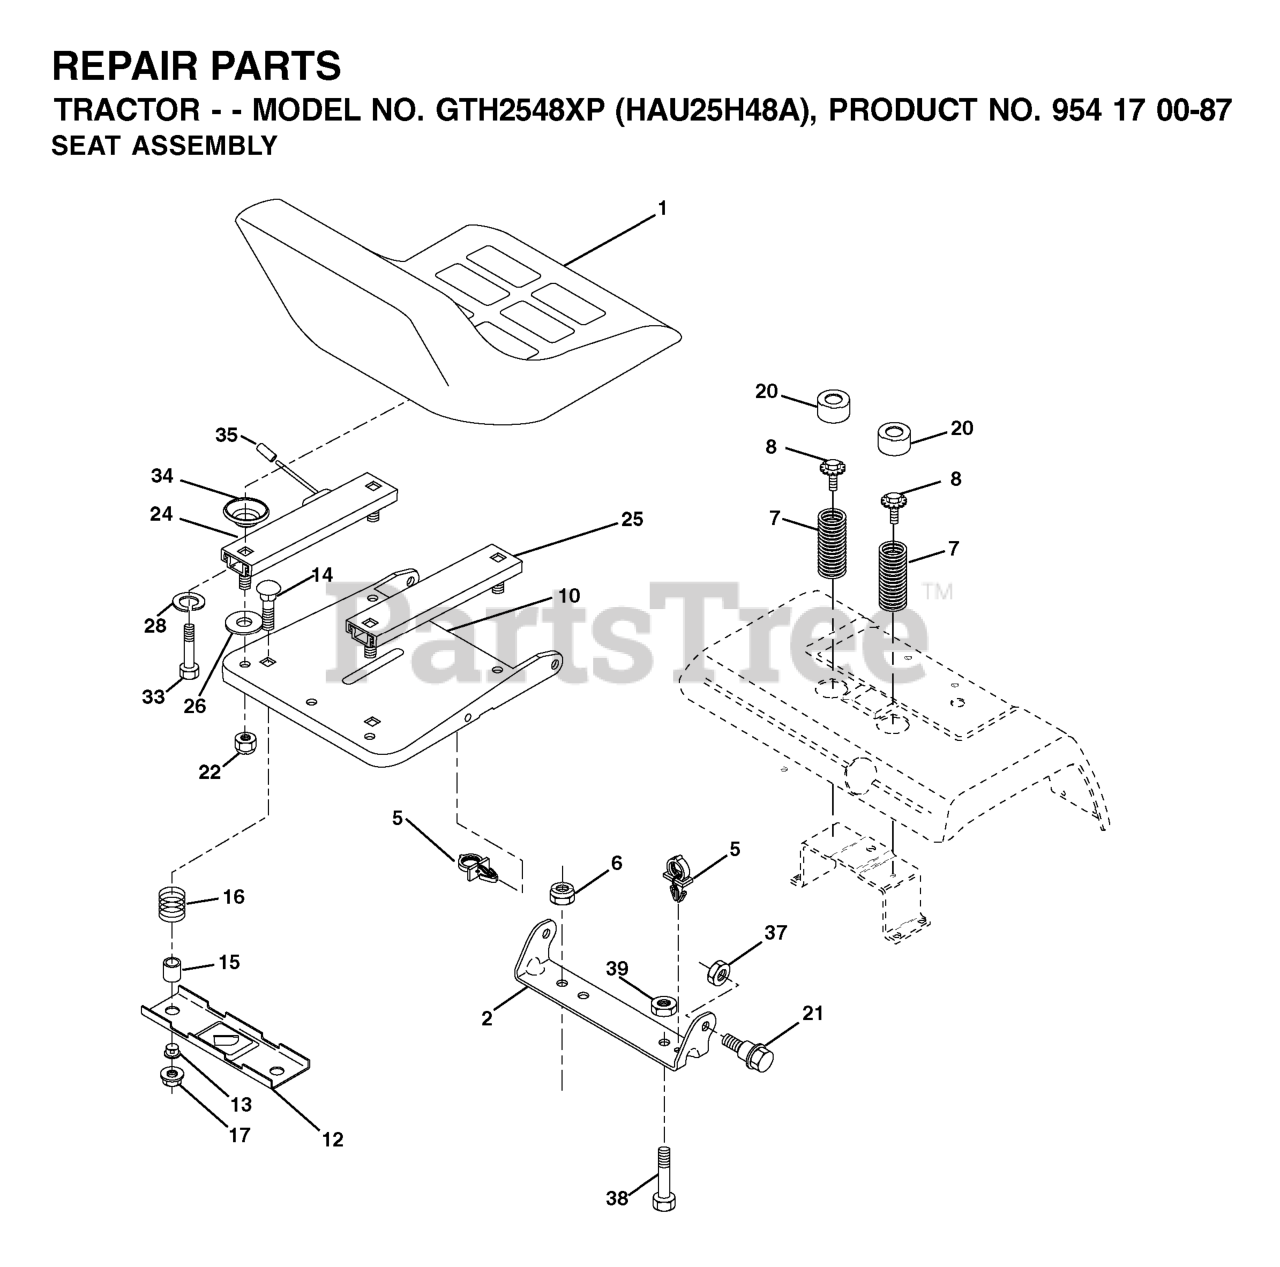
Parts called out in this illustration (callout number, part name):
1	SEAT
2	SEAT PIVOT BRKT
3	STRAP
6	NUT
7	SPRING COMPRESSION
8	BOLT.5/16-18UNCX3/4 W/SEMS.BLK
10	PAN SEAT
12	BRKT SWITCH
14	BOLT.ROUND.HEAD.SQUARE.NECK
15	SPACER SPLIT
16	SPRING COMPRESSED
17	NUT T
20	CAP SPRING
21	BOLT.SHOULDER.5/16-18
22	NUT.71038.31-18.HEX.NYLOCK
24	TRACK SLIDE, SEAT(L)
25	TRACK SLIDE, SEAT(R)
33	BOLT.FIN.HEX.5/16-18UNC X 1.00
35	CAP
37	NUT
38	BOLT, HEX 3/8-16X1
